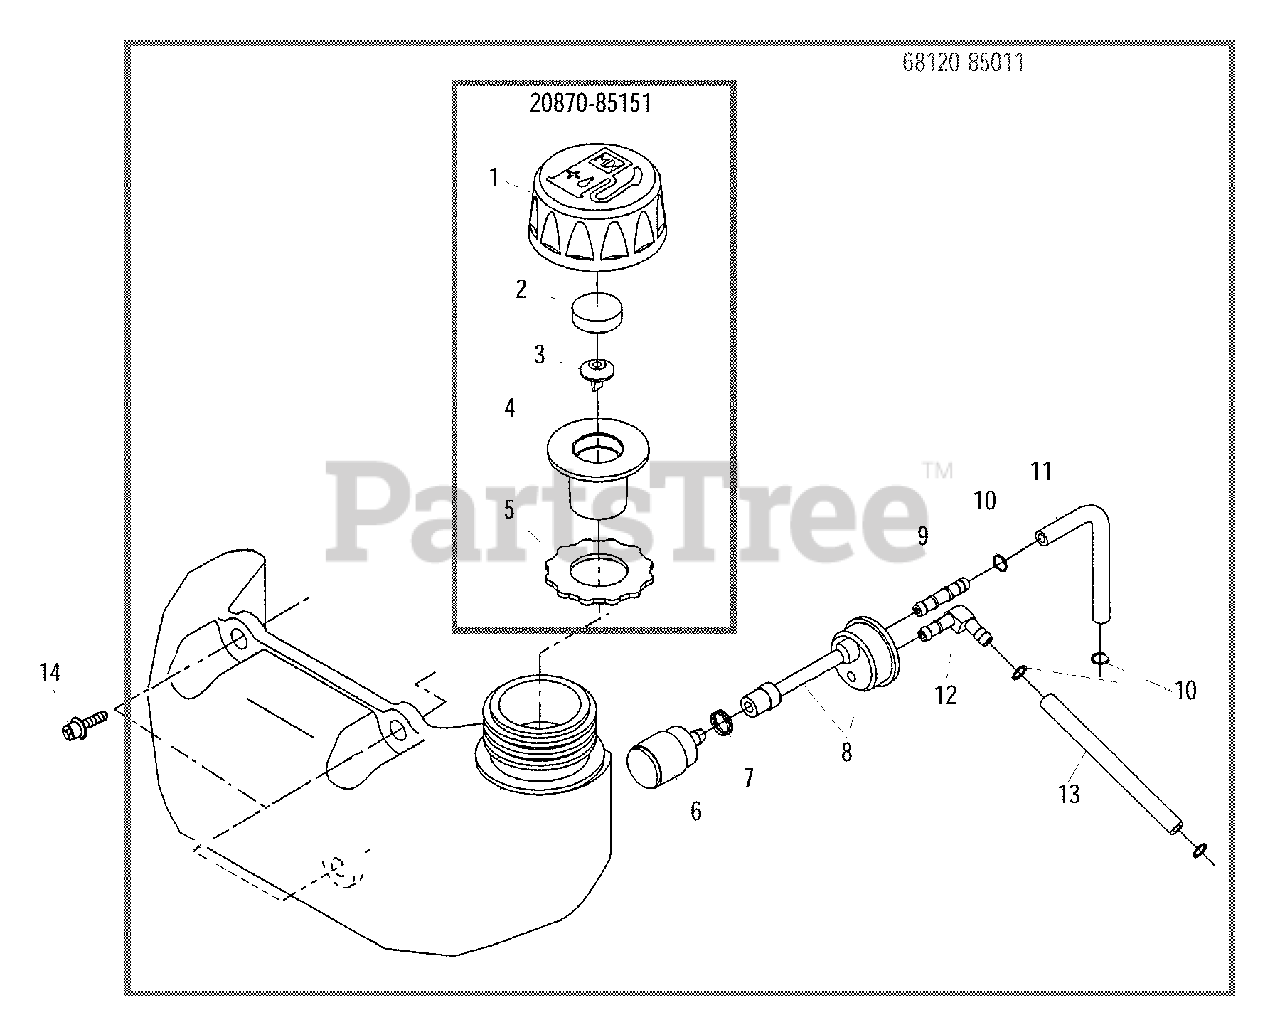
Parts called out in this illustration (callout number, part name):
1	CAP, FUEL
2	PACKING, VENT
3	VENT ASSY
4	HOLDER, VENT
5	GASKET, FUEL CAP
6	FILTER, FUEL 125-528
7	CLIP
8	GROMMET, FUEL WITH PIPE
9	CONNECTOR, PIPE
10	CLIP Ø6
11	PIPE, FUEL
12	CONNECTOR, PIPE
13	PIPE, RETURN
14	BOLT, ADHESIVE M5×20
20870-85151	CAP ASSY, FUEL
68120-85011	FUEL TANK ASSY
